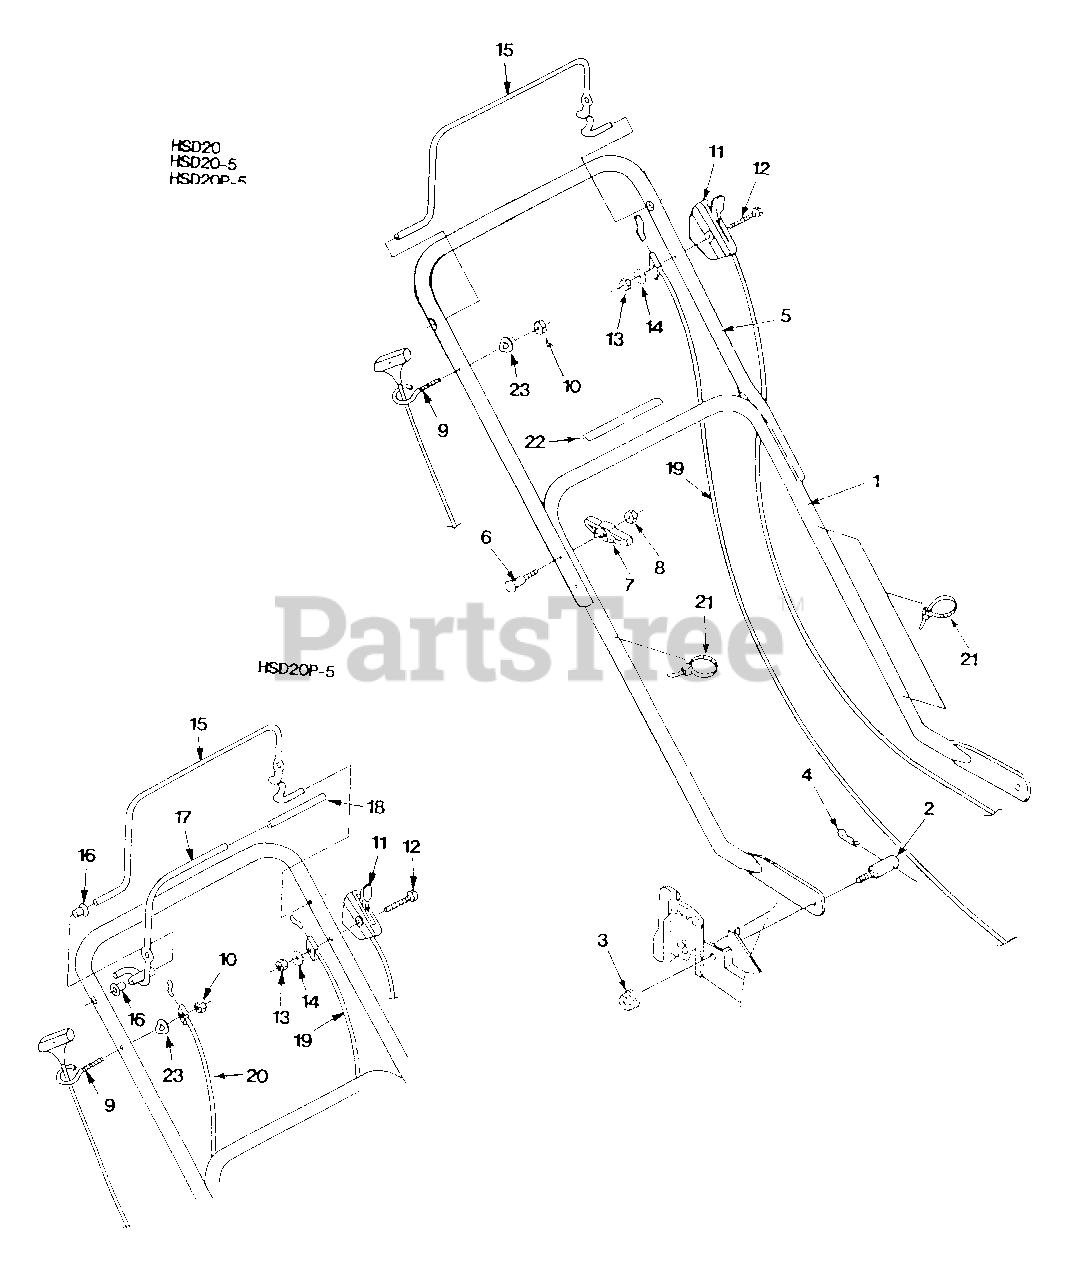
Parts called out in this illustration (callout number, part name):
1	Handle - lower
2	Stud - handle mounting
3	Nut - hex 5/16-18 flnge lock
5	Handle - upper
6	Bolt - carriage 5/16-18 x 2 - 1/4
7	Knob - handle, plastic
8	Nut - hex 5/16 - 18
9	Eyebolt - starter rope 1/4-20
10	Nut - hex 1/4-20 lock
11	Control - throttle w/cable
12	Bolt - hex 1/4-20 x 2
13	Nut - hex 1/4-20
14	Washer - lock 1/4 ext tooth
15	Bail - engine/blade control
16	Bushing - control bail
17	Bail - ground drive control
18	Sleeve - ground drive bail
19	Cable - engine/blade control
20	Cable - ground drive
21	Cable Tie
22	Decal - starting instructions
23	Washer - curved
